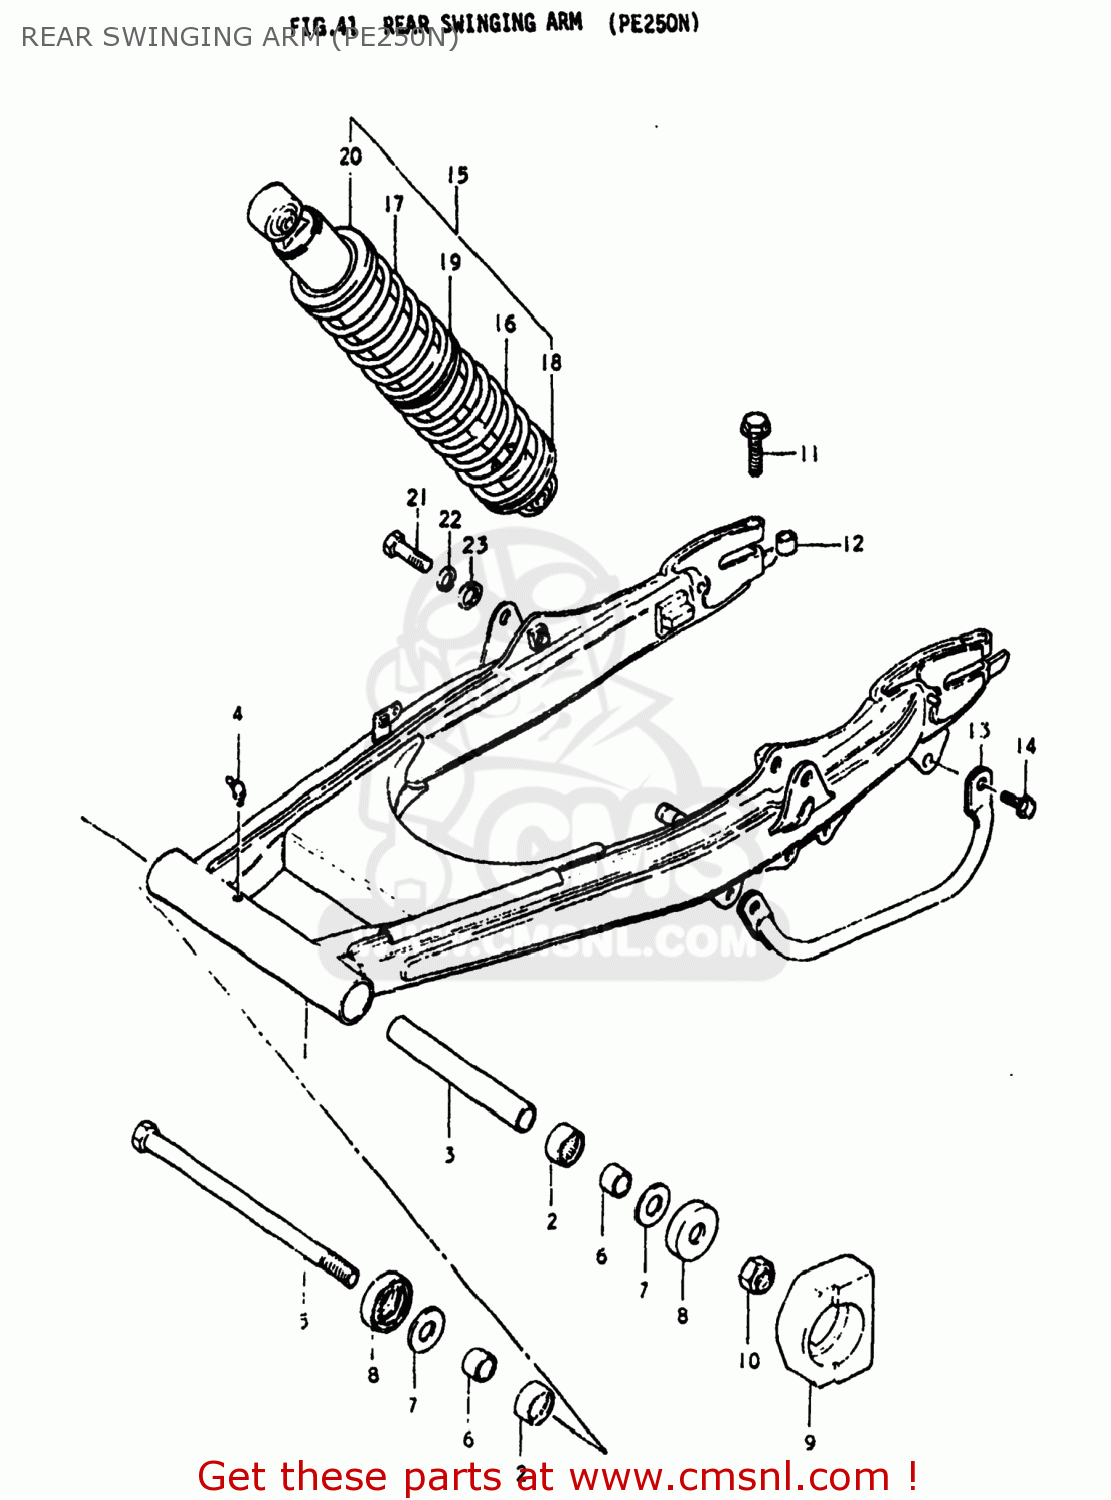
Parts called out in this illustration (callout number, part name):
1	SWING ARM ASSEMBLY,REAR
2	BEARING(22X29X20)
3	SPACER,REAR SWING ARM PIVOT
4	NIPPLE,GREASE
5	SHAFT,REAR SWING ARM
6	SPACER,RR SWGARM PIVOT
7	WASHER(14.2X34X1)
8	CVR,RR SWGARM DUST SEAL(OD:40)
9	BUFFER,CHAIN TOUCH DEFENSE
10	NUT 14MM
11	BOLT 8X55
12	SPACER
13	GUARD
14	BOLT
15	ABSORBER ASSEMBLY,REAR SHOCK
16	SPRING
17	SPRING
19	SPRING
20	GUIDE,SPRING
21	BOLT 10X40
22	LOCK WASHER
23	WASHER
